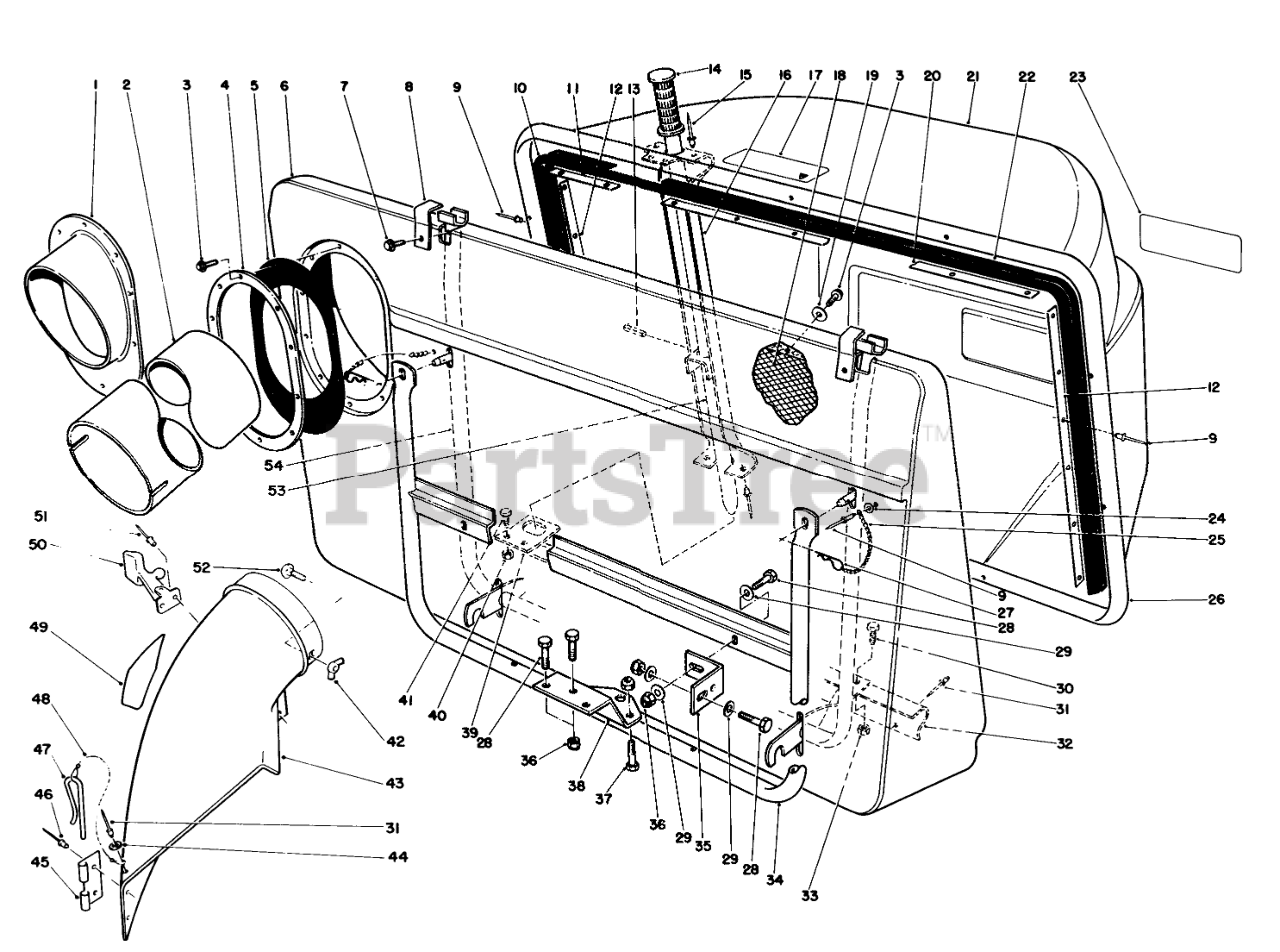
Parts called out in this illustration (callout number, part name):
1	DUCT ADAPTER
2	TUBE(ROUND&LONG)
3	SCREW-HWHTF
4	RING-RETAINING
5	RING-RETAINER, RUBBER
6	Bag Front
7	SCREW-HWH
8	RETNR PIVOT BRKT
10	RH BAG SEAL
11	RETNR TOP EXT.
12	BAG RETNR EXT.
13	PIN-ROLL
15	RIVET-POP
16	DUMP HDLE CHANL WA
17	Decal Warning
18	Screen Bag
19	WASHER-FLAT
20	EXTRUSION BAG RETAINER
21	REAR GRASS BASKET
22	Seal-Bag LH.
23	EASY EMPTY BAG DECAL
24	WASHER
25	10 LINK CHAIN W/O HOOK
26	BAG SUPT ASM FRM
27	PIN-HAIR
28	SCREW-HH
29	WASHER-PLAIN
30	SCREW-HH
31	RIVET-BLIND
32	FRAME SUPT BRKT B
33	NUT-LOCK, CONE
34	BAG SUPPORT WA
35	MTG BRACKET
36	NUT-LOCK, NI
37	SCREW-HH
38	MTG PLATE B
39	Hanger-Frame Lower
40	NUT-LOCK, CONE
41	SCREW-HH
42	NUT-WING SPECL
43	Chute Assembly (Incl. Ref. #31 & 44-51)
44	WASHER-PLAIN
45	BRACKET-MOUNTING, CHUTE
46	RIVET-BLIND
47	PIN-LOCKING, CHUTE
48	LANYARD
49	DECAL-DANGER
50	Latch-38"
51	RIVET-POP
52	BOLT-CARR
53	DUMP HANDLE ASM
54	Bag Frame
